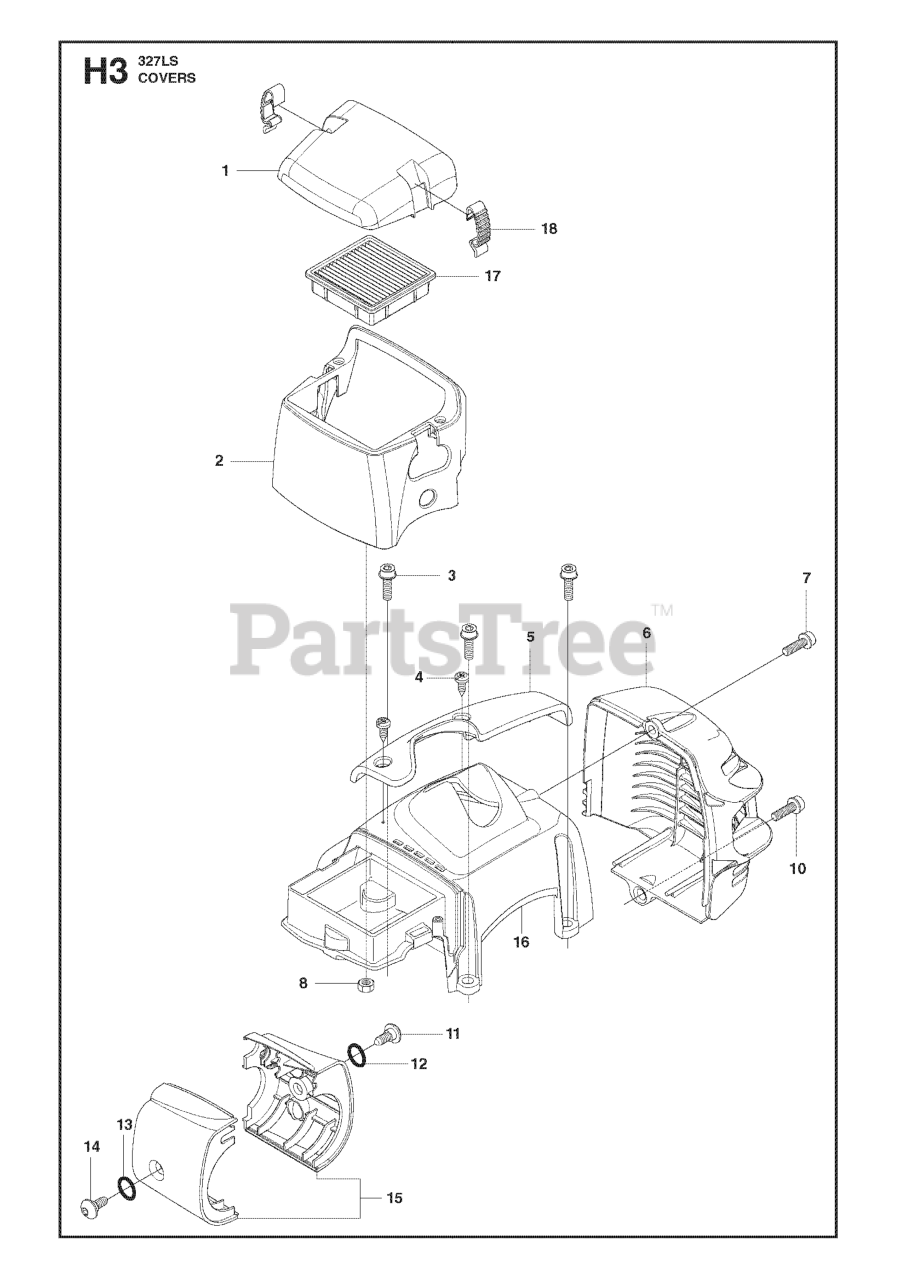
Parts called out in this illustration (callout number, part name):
1	FILTER COVER
3	SCREW IHSCFMO
5	ARM PROTECTION
6	HEAT PROTECTOR
7	SCREW IHSCFTO
10	SCREW IHSCFMO
11	SCREW MT5X11
12	O-RING 8X1.6
13	O-RING 8X1.6
14	SCREW MT5X11
16	CYLINDER COVER ASSY
